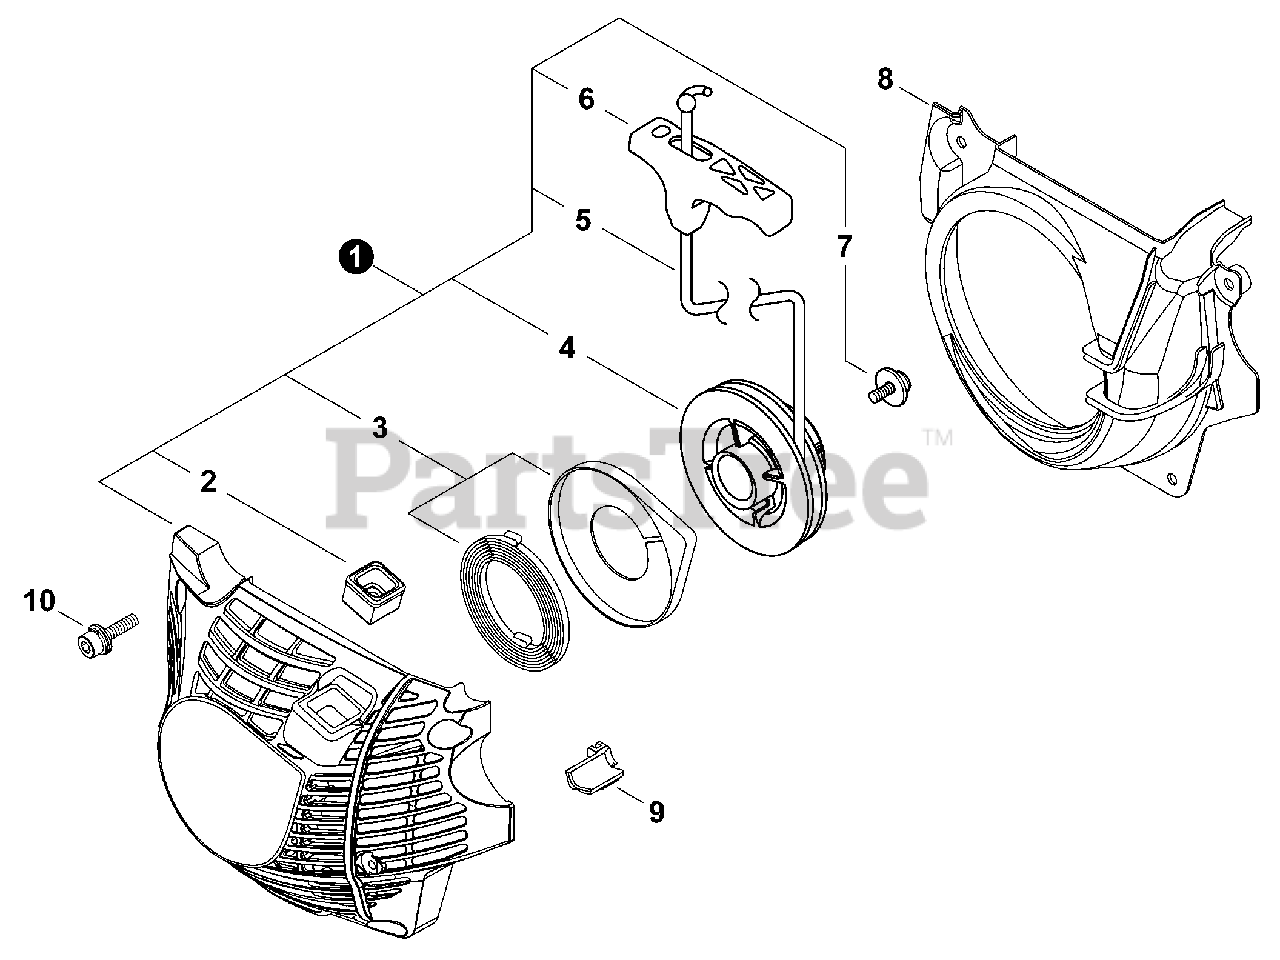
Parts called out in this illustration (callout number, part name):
1	STARTER ASSY, RECOIL
2	GUIDE, ROPE
3	RECOIL SPRING W/CASE
4	REEL, ROPE
5	ROPE, STARTER
6	GRIP, STARTER
8	COVER, FAN
9	GROMMET, NEEDLE
10	BOLT M4×16
